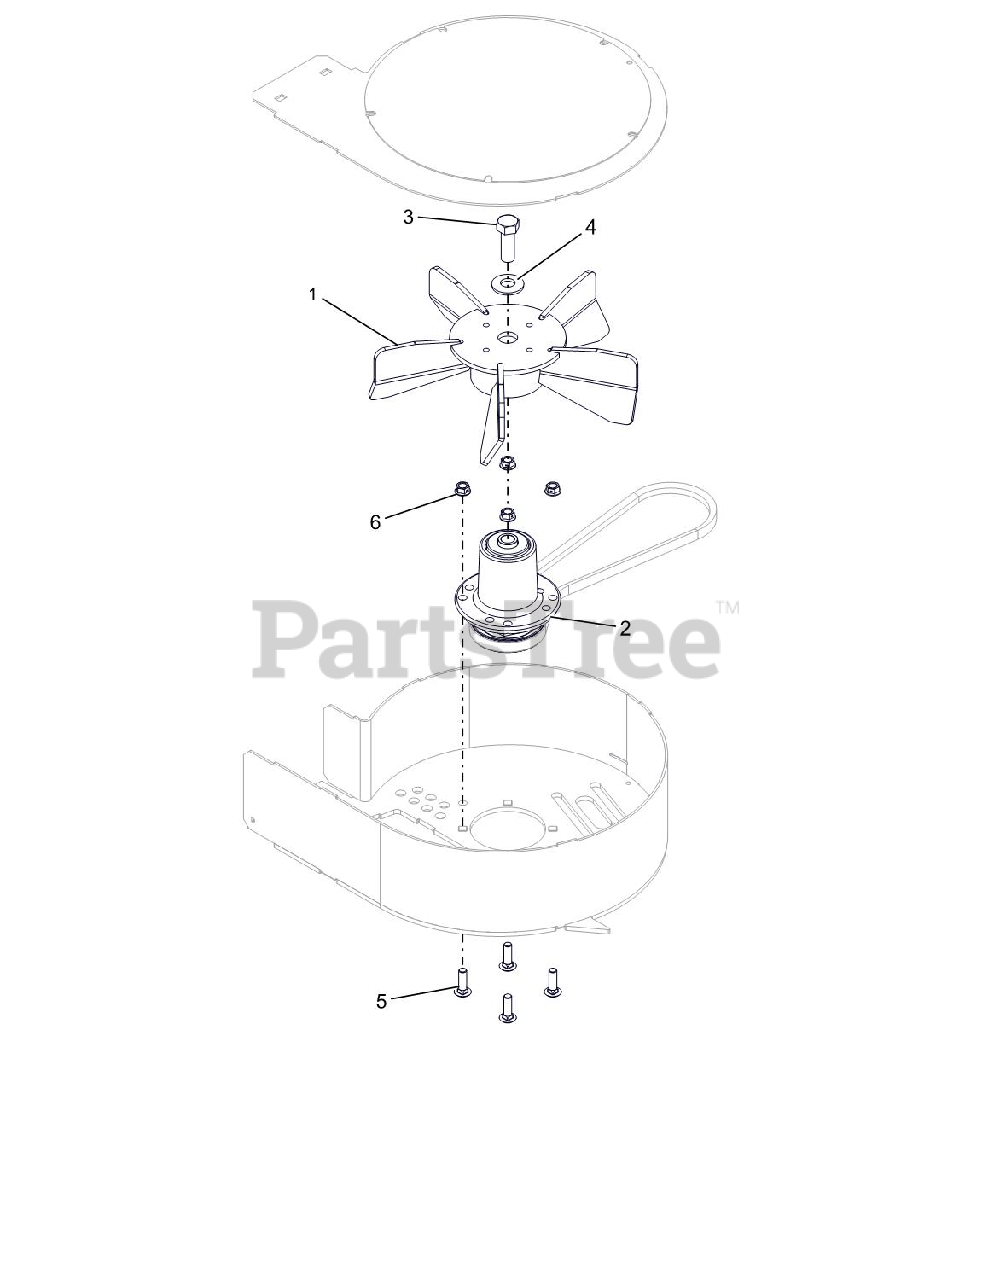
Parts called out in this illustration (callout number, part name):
1	WLDMT, FAN BAGGER
2	SPINDLE ASSEMBLY, SERVICE
3	BLT-HEX .62-18X1.75 GR8 YWZC
4	WSHR-BLVL .669X1.535X.138
5	BLT-RDHDSQNK .38-16X1.25 G5YZ
6	NUT-LK-CTR-FLG .38-16 YWZC
